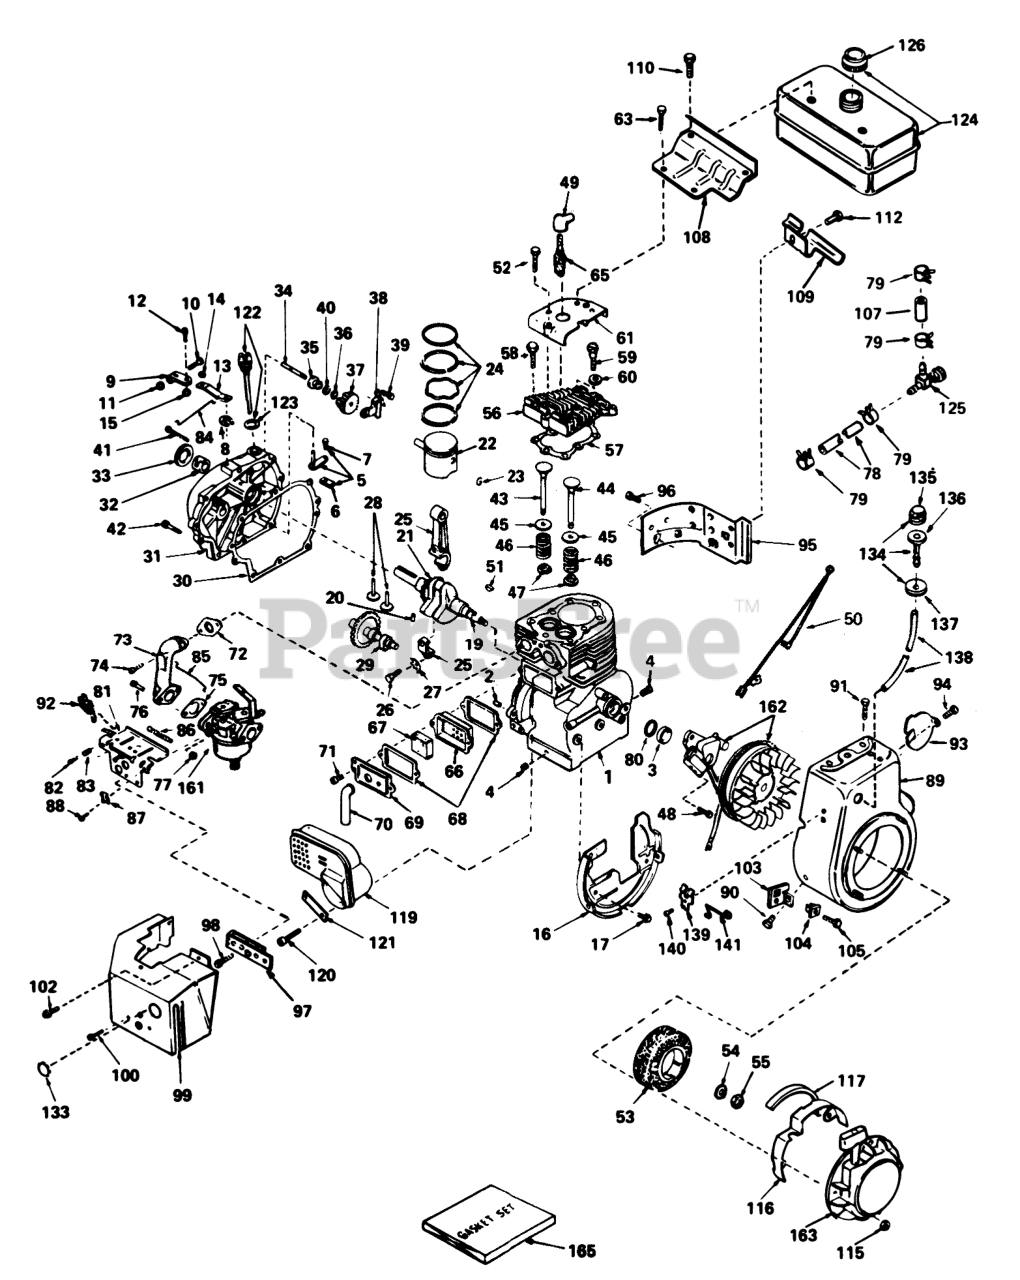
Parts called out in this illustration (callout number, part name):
1	Cylinder Assy. (Incl. Nos. 2, 3 & 4)
2	Pin-Dowel
3	Oil Seal
4	Plug-Drain, Oil (SQH 1/4-18)
5	Rod Assy., Governor (Incl. Nos. 6 & 7)
6	Yoke-Governor
7	Screw (6-40x5/16)
8	Ring-Retaining
9	Clamp-Lever, Governor
11	Nut-Lock
12	Screw
13	Lever-Governor
14	Washer-Lock
15	Nut-Lock
16	Baffle Blower Housing
17	Screw (1/4-20x19/32)
19	Crankshaft Assy. (Incl. Nos. 20 & 21)
20	Pin, Groove
21	Gear, Crankshaft
22	Piston, Pin & Ring Assy. (Std.) (Incl. Nos. 23 & 24)
22	Piston, Pin & Ring Assy. (.010 oversize) (Incl. Nos. 23 & 24)
22	Piston, Pin & Ring Assy. (.020 oversize) (Incl. Nos. 23 & 24)
23	Ring-Retaining, Piston Pin
24	Ring Set (Std.)
24	Ring Set (.010" OS)
24	Ring Set (.020" OS)
25	Rod Assy., Connecting (Incl. Nos. 26 & 27)
26	Bolt, Connecting Rod
27	Dipper-Oil
28	Lifter-Valve
29	Camshaft (Mech. Comp. Release)
30	Gasket, Cylinder Cover
31	Cover, Cylinder (Incl. Nos. 32, 33 & 34)
32	Bushing, Crankshaft
33	Seal, Oil
34	Shaft-Governor
35	Spool-Governor
36	Ring-Retaining
37	Gear Assy., Governor (Incl. No. 40)
38	Bracket-Gear, Governor
39	Screw (10-32 x 35/64)
40	Washer-Flat
41	Screw (1/4-20 x 1-1/4)
43	Valve, Intake (Std.) (Incl. No. 47)
43	Valve, Intake (1/32" oversize) (Incl. No. 47)
44	Valve, Exhaust (Std.) (Incl. No. 47)
44	Valve, Exhaust (1/32" oversize) (Incl. No. 47)
45	Cap-Spring, Valve
46	Spring-Valve
47	Keeper-Spring, Valve
49	Cover-Spark Plug
50	Wire, Ground
51	Key-Flywheel
52	Screw (1/4-20 x 1/2)
53	Hub & Screen Assy., Starter
54	Washer
56	Head Cylinder
57	Gasket-Cylinder Head
58	Screw (5/16-18x1-1/2)
59	Screw (5/16-18x1-25/32)
60	Washer-Flat
61	Cover, Cylinder Head
63	Screw
65	Plug, Spark (J17LM or equiv.)
65	Plug, Spark (Champion RCJ-8)
66	Body-Breather
67	Element-Breather
68	Gasket-Breather
69	Cover-Valve
70	Tube-Breather
72	Gasket-Intake
73	Pipe-Intake
74	Screw (T-30, 5/16-18x1-3/32)
75	Gasket, Carburetor
76	Screw (1/4-28x1)
77	Nut and Lock Washer (1/4-28)
78	Line-Fuel
79	Clamp-Line, Fuel
80	Gasket Stator
81	Control Assy., Speed (Incl. Nos. 82, 83, 86 & 92)
82	Screw
83	Spring-Compression
84	Link, Governor
85	Link-Throttle
86	Spring, Extension
87	Conduit
88	Screw (10-32 x 3/8)
89	Housing, Blower
90	Screw, Hex Hd.
91	Screw (5/16-18x3/4)
92	Terminal
94	Screw (8-32 x 3/8)
95	Extension, Blower Housing
97	Bracket-Carburetor
98	Screw (8-32x27/64)
99	Cover, Carburetor
100	Screw (10-32 x 3/8)
102	Screw (10-32x1/2)
103	Bracket
104	Grommet
105	Screw
107	Line-Fuel (8.62)
108	Bracket-Tank, Fuel (Black)
109	Bracket-Tank, Fuel
110	Screw (1/4-15x7/8)
112	Screw (1/4-20x19/32)
115	Nut and Lock Washer (1/4-28)
116	Guard, Starter
117	Seal, Snowguard
119	Muffler
120	Screw, Hex Hd.
121	Plate-Locking
122	Dipstick, Oil (Incl. No. 123)
123	Gasket
124	Tank Assy., Fuel (Incl. No. 126)
125	Valve-Shut Off
126	Cap, Fuel
134	Primer Assy. (Incl. Nos. 135, 136 & 137)
135	33164A GILO"HITCH A
136	Body Primer
137	Retainer, Primer Bulb
138	Line, Primer
139	Bracket, Choke Wire
140	Screw (8-32 X 5/16)
141	Wire, Choke
161	Carburetor (Incl. No. 75)
162	Magneto (The complete magneto is not available as an assembly. The magneto number is shown for reference purposes only. Order component parts individually, as shown in parts list.)
163	Starter, Rewind
165	Gasket Set
